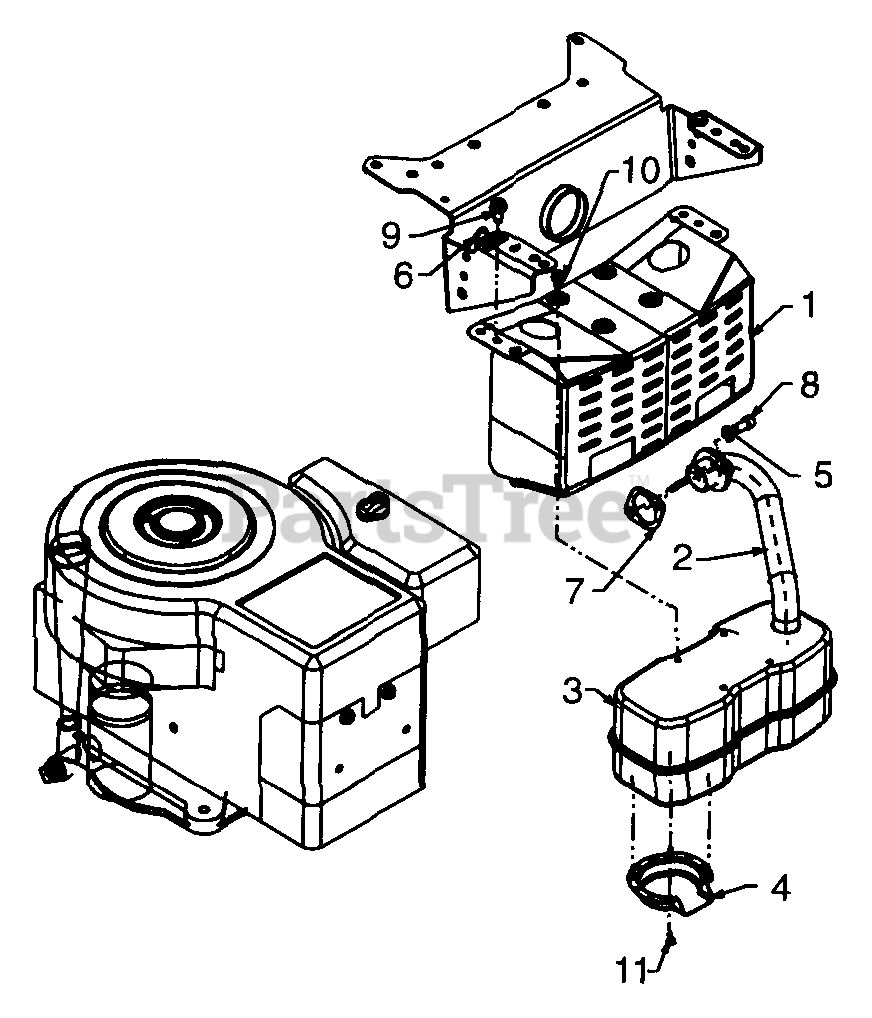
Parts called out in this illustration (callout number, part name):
2	Exhaust Pipe
3	Muffler
4	Muffler Deflector
5	L-Wash. 5/16" I.D.
6	Clamp
7	Exhaust Gasket
8	Socket Hd. Bolt 5/16-18 x .62" Lg.
9	Hex Wash Hd. TT-Tap Scr. 5/16-18 x .62" Lg.
10	Hex Wash. TT-Tap Scr. 1/4-20 x .5" Lg.
11	Hex Slot Scr. #8-32 x .38" Lg.
